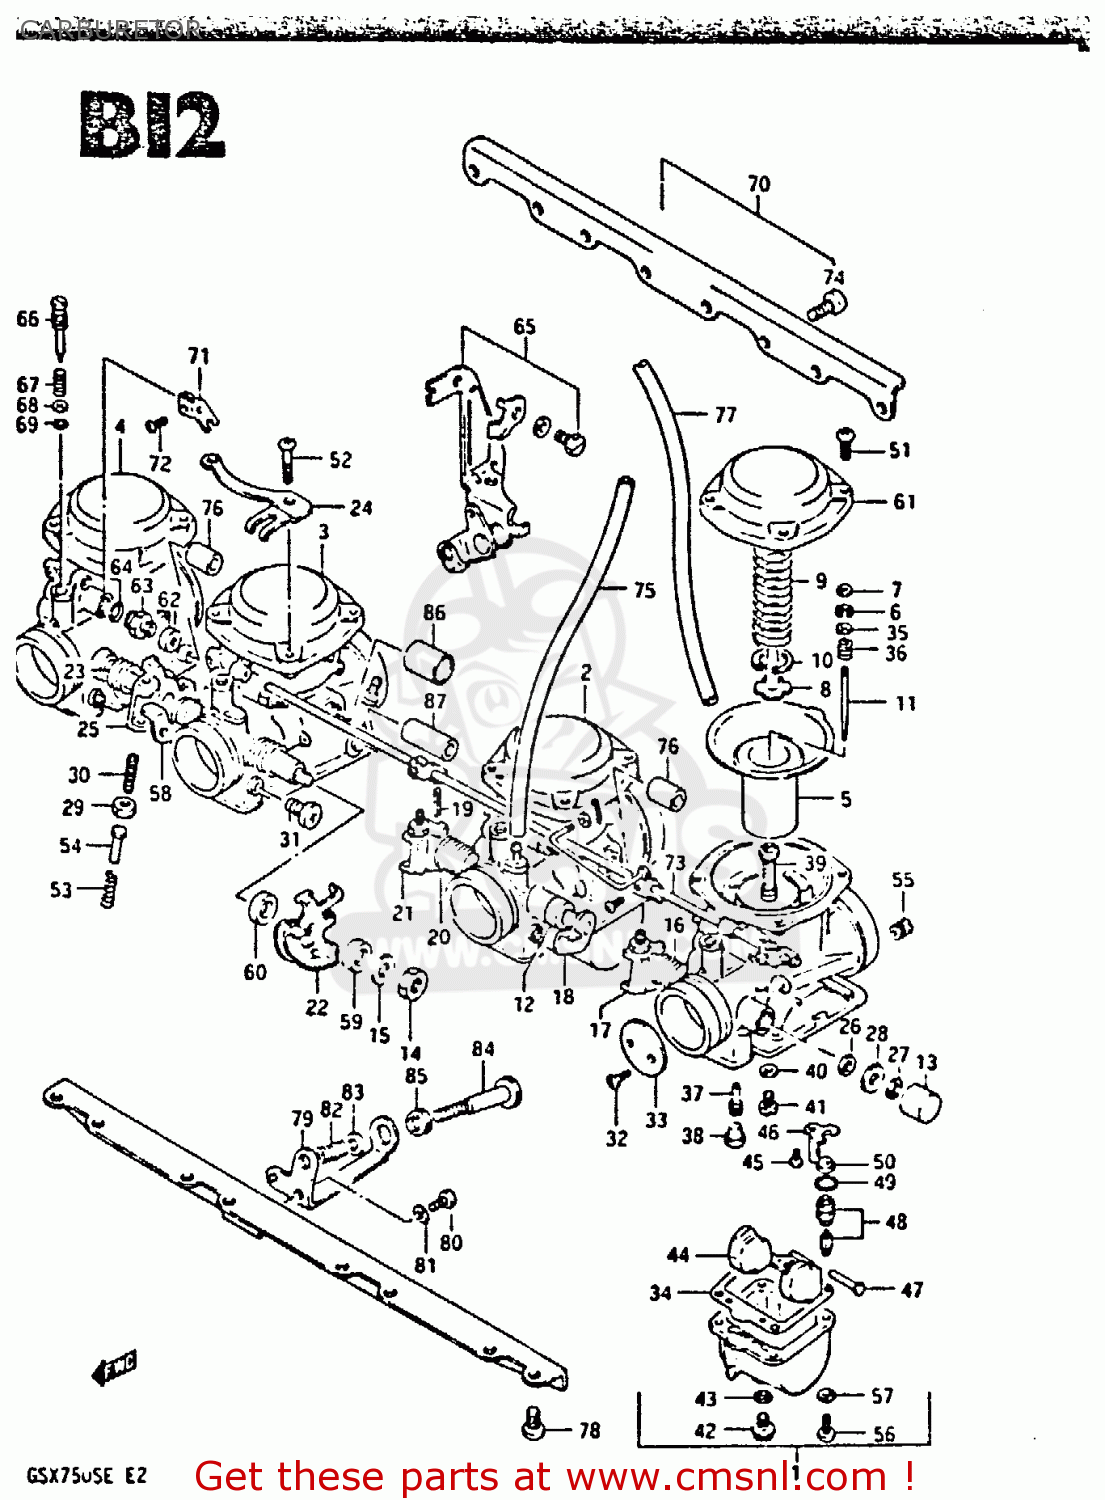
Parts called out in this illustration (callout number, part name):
1	CARBURETOR, NO. 1
2	CARBURETOR, NO. 2
3	CARBURETOR, NO. 3
4	CARBURETOR, NO. 4
5	DIAPHRAGM,CARBURETOR
6	CLIP,NEEDLE
7	RING
8	HOLDER,GUIDE
9	SPRING,DIAPHRAGM
10	E RING
11	NEEDLE,JET
12	GASKET
13	CAP
14	NUT
15	WASHER
16	SPRING,THROTTLE SHAFT
17	SHAFT,THROTTLE
18	SHAFT,THROTTLE
19	PIN,THROTTLE SHAFT
20	SPRING,THROTTLE SHAFT
21	LEVER,THROTTLE SHAFT
22	LEVER ASSEMBLY,THROTTLE
23	SPRING,THROTTLE SHAFT
24	BRACKET
25	SHAFT,THROTTLE
26	SEAL
27	E RING
28	GASKET,THROTTLE SHAFT (NAS)
29	NUT
30	SCREW
31	SCREW
32	SCREW
33	VALVE,THROTTLE (BUTTERFLY)
34	GASKET,FLOAT CHAMBER (NAS)
35	WASHER
36	SPRING
37	JET,PILOT(45)
38	PLUG,NEEDLE JET
39	JET,NEEDLE(Y-7)
40	WASHER,NEEDLE NOZZLE
41	JET,MAIN(117.5)
42	PLUG,DRAIN
43	GASKET (NAS)
44	FLOAT
45	SCREW
46	PLATE,NEEDLE VALVE FITING
47	PIN,FLOAT
48	VALVE ASSEMBLY,NEEDLE
49	O-RING,NEEDLE VALVE
50	FILTER
51	SCREW
52	SCREW
53	SPRING,THROTTLE SCREW
54	PIN,THROTTLE LEVER
55	JET,AIR(190)
56	SCREW
57	LOCK WASHER
58	SHAFT,THROTTLE
59	RING
60	RING
61	COVER
62	CAP,STARTER VALVE
63	GUIDE SCREW,PLUNGER
64	O RING
65	BRACKET ASSY
66	SCREW,PILOT AIR
67	SPRING
68	GASKET
69	O-RING
70	FLANGE ASSY
71	LEVER
72	SCREW,THROTTLE ADJUST
73	SHAFT,STARTER
74	SCREW 5X12
75	HOSE 4.5X8X390
76	NIPPLE,CARBURETOR
77	HOSE (5*8*400)
78	SCREW
79	BRACKET,THROTTLE ADJUST
80	SCREW 5X10
81	LOCK WASHER
82	SPRING
83	WASHER
84	ADJUSTER
85	BUSH
86	HOSE
87	NIPPLE,CARBURETOR
